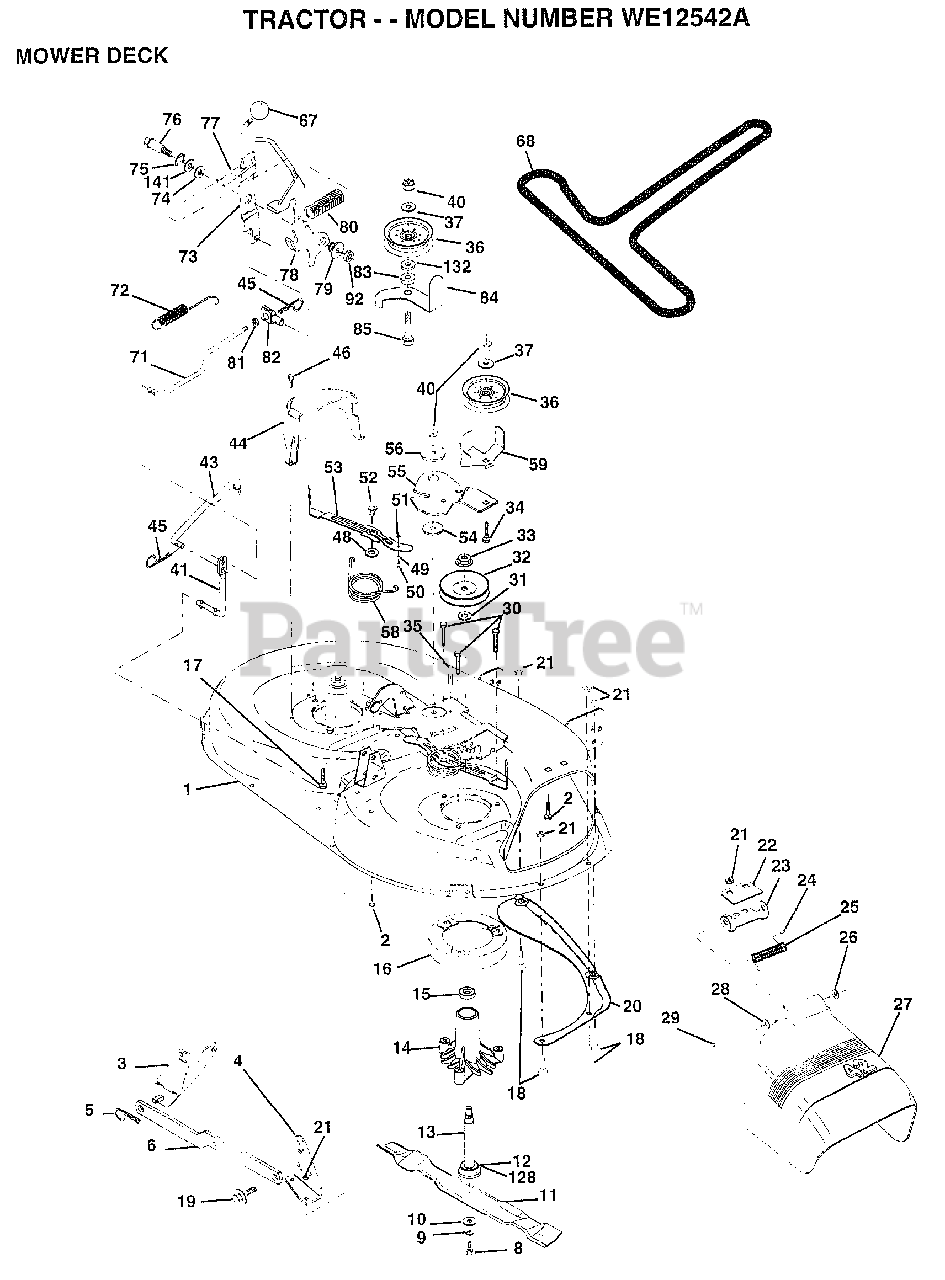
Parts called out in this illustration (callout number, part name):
1	DECK.WELD.42.
2	BOLT
3	BRKT ASM SWAY BAR
4	BRKT DECK SW BAR
8	BLADE BOLT
10	WASHER.HARD.BLADE
11	"BLADE.42"" HIPERF"
12	BEARING.BALL
14	HSG ASM MANDREL
15	BEARING
16	STRIPPER RND MWR
17	BOLT RDHD 3/8-16
18	BOLT
19	BOLT SHD 5/16-18
21	NUT LTV
22	STIFFENER BRKT
23	DEFLECTOR BRKT
24	CAP-SLEEVE LT
25	SPRING TORSION
26	NUT PUSH M
27	DEFLECTOR.SHIELD
28	WASHER
29	HINGE ROD
30	"SCREW-THD ROLL,WA"
31	WASHER
32	PULLEY.MANDREL.42
34	BOLT
35	XMAS TREE FASTNER
36	FLAT IDLER PULLEY
37	WASHER
41	PIVOT ROD
43	ROD CLUTCH W/NIBS
44	GUARD MAND LH BLK
45	RETAINER M
46	SCREW.1/4-20X5/8
48	HARD SMALL WASHER
49	ROLLER ASM-CAM
50	SHOULDER BOLT
51	LOCKNUT
52	BOLT.SHLD.5/16-18
54	HARDENED WASHER
55	ARM-IDLER
56	SPACER RETAINER
58	SPRING TORSN BRAK
59	GUARD IDLER TUV
67	KNOB T(3/8 HOLE)
68	BELT.V.T-PATH
71	ROD CLUTCH 38/42
72	RETURN SPRING
73	CLUTCH ARM SECOND
74	WASHER
75	RING
76	SHOULDER BOLT
77	SPRING KEEPER
78	LEVER ASM-CLUTCH
79	BUSHING
80	SPRING.CLUTCH.MWR
81	TRUNION ADJ
82	NUT
83	WASHER
84	"KEEPER-BELT,FIXED"
85	BOLT RDHD 3/8-16
92	NUT
128	WASHER.FELT.
132	WASHER GT
141	WASHER .T
